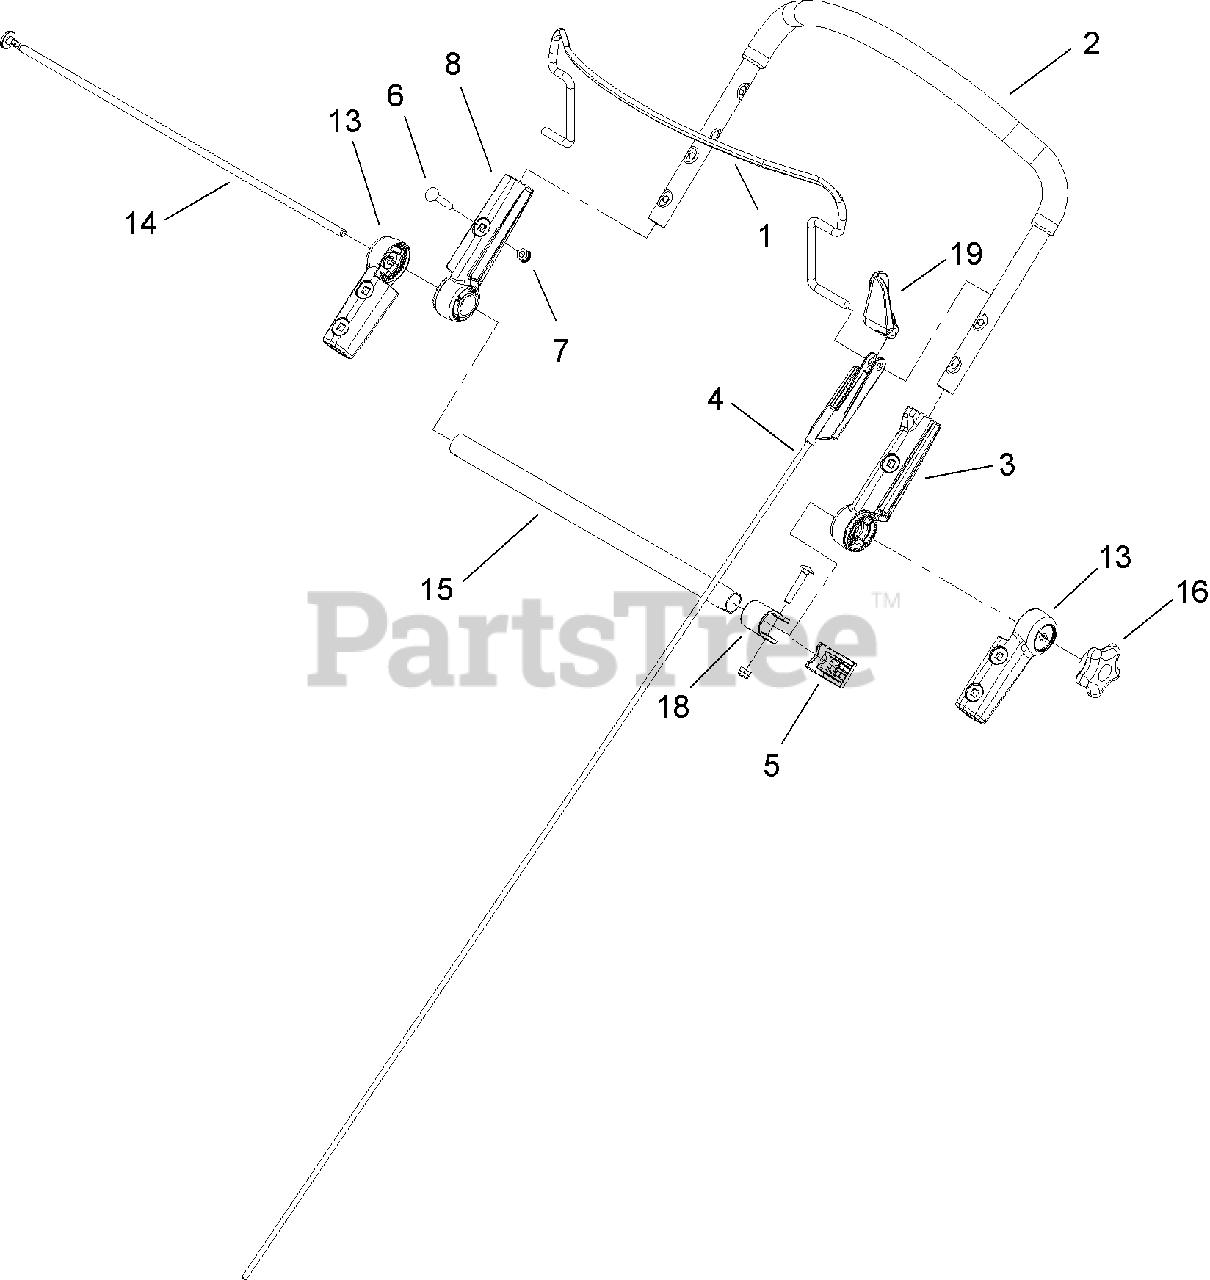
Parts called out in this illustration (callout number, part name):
2	HANDLE ASM
3	MOUNT-HANDLE, LH
4	CABLE-BRAKE
5	SUPPORT-GUIDE, CABLE
6	SCREW-CARR
7	NUT-LOCK, NI
8	MOUNT-HANDLE, RH
13	MOUNT-HANDLE, LOWER
14	ROD-THREADED
18	SUPPORT-CABLE
19	STOP-PIVOT
